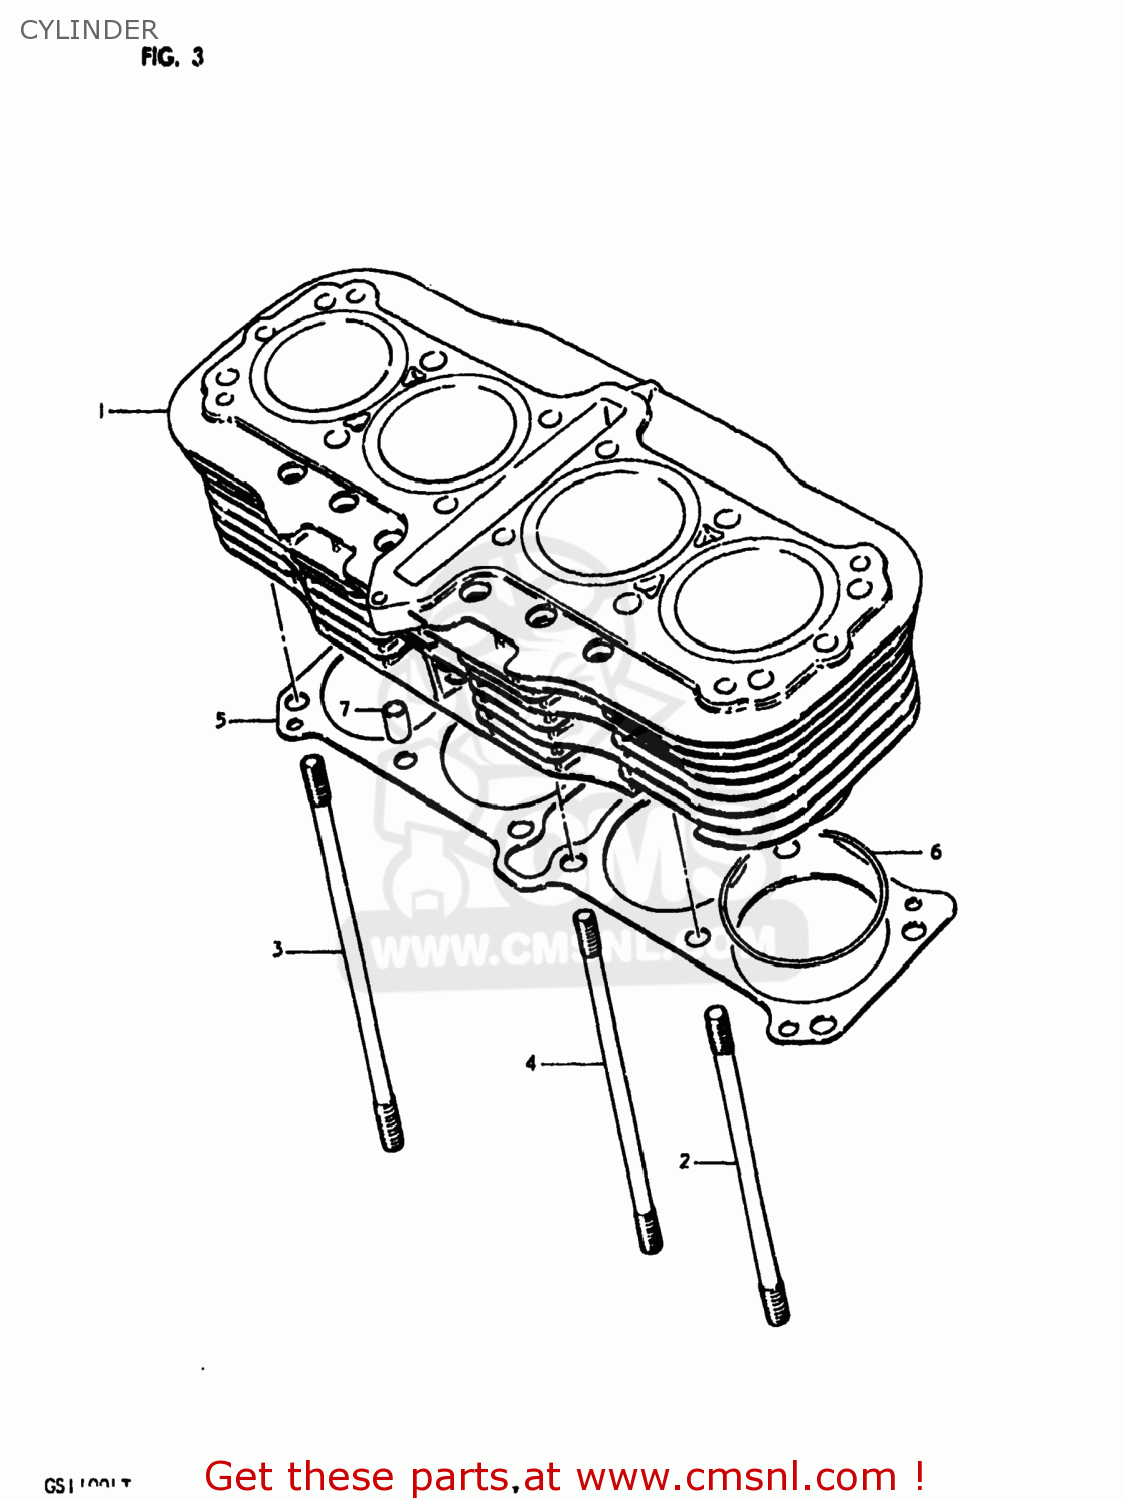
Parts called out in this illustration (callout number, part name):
1	CYLINDER
2	BOLT,STUD
3	STUD
4	BOLT,STUD
5	GASKET,CYLINDER (MCA)
6	O RING(D:2,ID:74)
7	PIN
